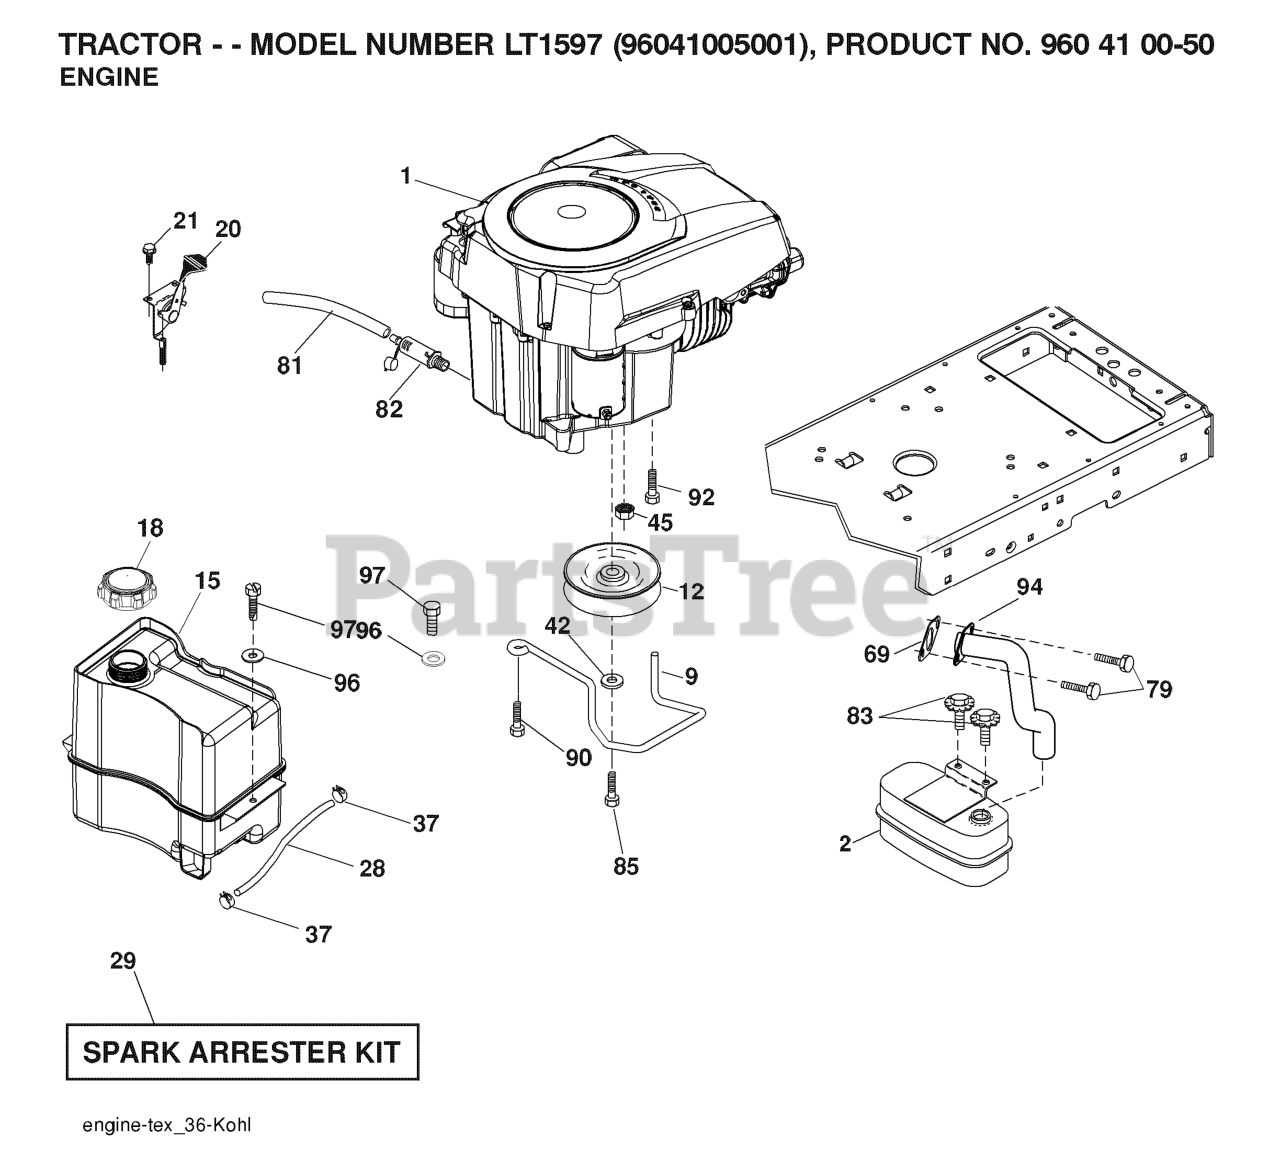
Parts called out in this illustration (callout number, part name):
1	CONSOLE.ASSY.RZ.REFRESH.RH
2	CONSOLE.LH.ASM
3	TANK.ASM3"NECK.NOCAP.NOSHDRZ17
4	CAP ASSY FUEL 3" GRAY
5	CABLE.THROTTLE.37"
6	CANNISTER, CARBON
7	RP IGNITION SWITCH
8	RP SWITCH.PTO.TERMINAL.STD.RED
9	SWITCH.INTLK.RZ.RFRSH.BUTTON
10	KNOB.ROUND.BALL.BLACK
11	CONTROL.PANEL.RZ.REFRESH.RH
12	BATTERY, 12 V 300 AMP DRY
13	BRACKET.PNT.MOUNT.BATTERY.EDIP
14	BOX.PNT.BATTERY.RZ.EDIP
15	TERMINAL COVER
17	VALVE.FUEL.CHECK
18	FUEL.HOSE.SHUT.OFF.ASM.10".3"
19	SOLENOID.STARTER.BRASS.PLUNGER
20	HARNESS.BTTRY.CABLE.RZ.REFRESH
21	HOSE.3/16".VAPOR.LINE.33"LGTH
22	BUSHING OUTLET T
23	GROMMET.ROV.SENTEC
24	STEM FUEL TANK
25	GUAGE.SRVCMNDR.HRMTR.
26	KEY MLD GEN DELTA
27	CABLE POSITIVE, LONG
28	BRACKET, CANISTER
29	HOOK.J.BATTERY
30	SCR 1/4-20 X 5/8 BTN SKT HD ZD
31	SCREW.PAN.HEAD.#10
32	SCREW.BUTTONHD.10-24X1/2.(2 2)
33	SCREW
34	SCREW 6-19X.437
35	RP BOLT 5/16-18 X3/4 ZN/YEL GR
36	HCS 5/16-18 X 5/8 GR 5 ZD
37	RHSNB 3/8C X 1
38	NUT.1/4-20.HEX.NYLOC.ZD
39	5/16-18 NYLOC FLANGE NUT
40	NUT 3/8-16 HEX FLG NYLOC ZD
